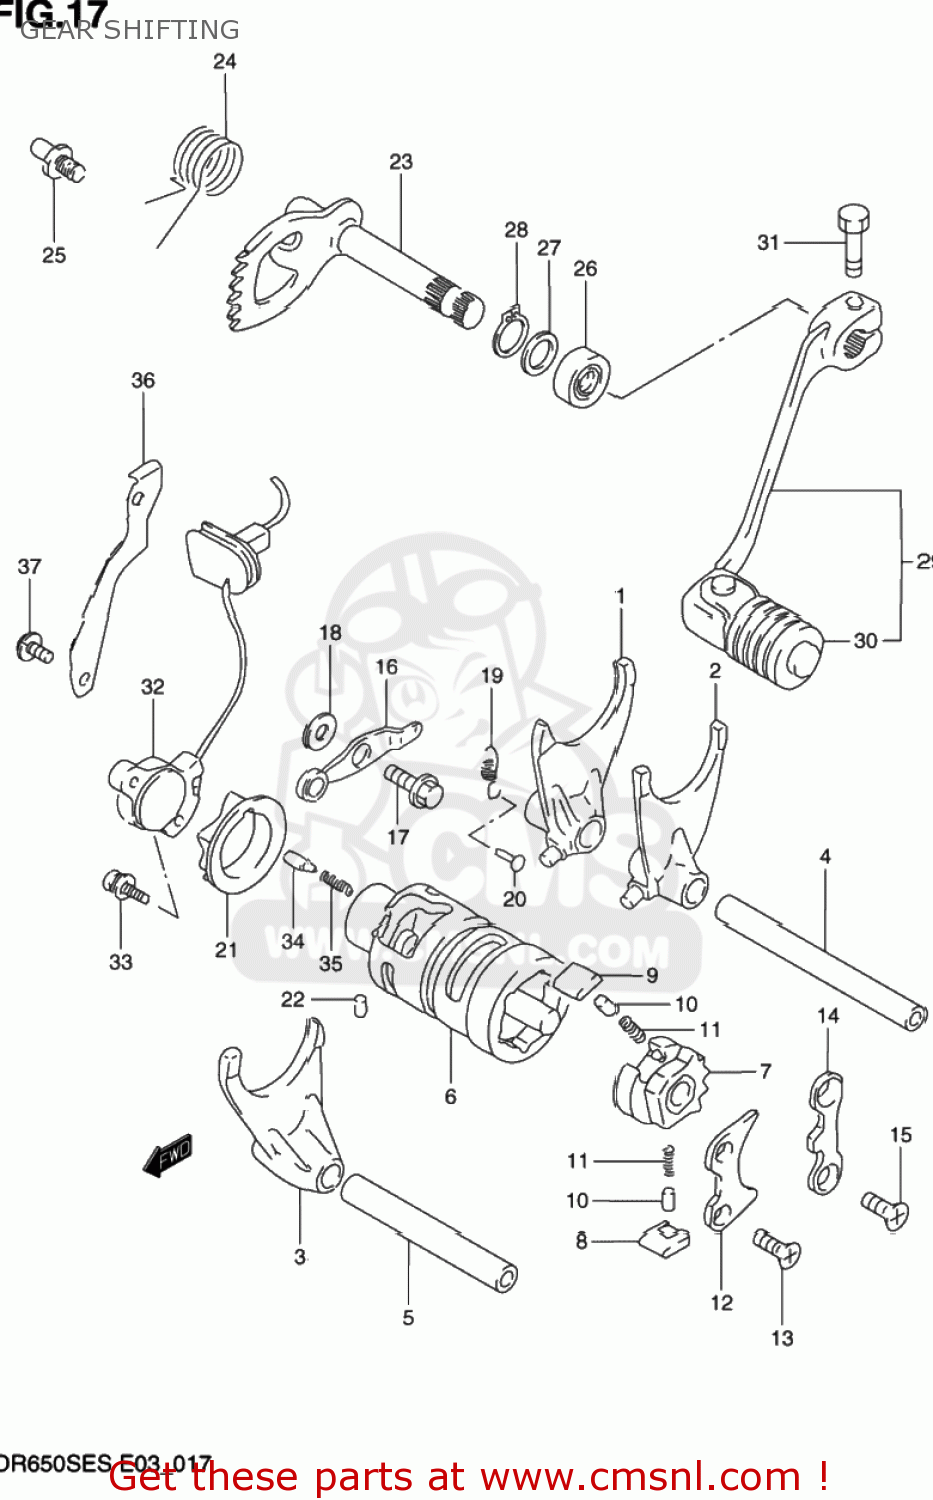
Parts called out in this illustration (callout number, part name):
1	FORK,GEAR SHIFT NO.1
2	FORK,GEAR SHIFT NO.2
3	FORK,GEAR SHIFT NO.3
4	SHAFT,GEAR SHIFT FORK
5	SHAFT,GEAR SHIFT FORK
6	CAM,GEAR SHIFT
7	GEAR,GEARSHIFT CAM DRIVE
8	PAWL,GEAR SHIFT NO.1
9	PAWL,GEAR SHIFT NO.2
10	PIN(5X8)
11	SPRING
12	LIFTER,GEAR SHAFT PAWL
13	SCREW
14	STOPPER,GEAR SHIFT POLE
15	SCREW
16	STOPPER,GEAR SHIFT CAM
17	BOLT
18	WASHER
19	SPRING
20	RIVET
21	PLATE,SHIFT CAM STOPPER
22	PIN 4X6
23	SHAFT,GEAR SHIFT
24	SPRING
25	STOPPER,GEAR SHIFT CAM
26	OIL SEAL
27	WASHER
28	CIRCLIP,12 MM
29	LEVER ASSY,GEAR SHIFT
30	RUBBER,GEAR SHIFT PEDAL
31	BOLT
32	BASE ASSY,NEUTRAL SW TERMINAL
33	SCREW
34	PIN(5X15.5)
35	SPRING
36	CLAMP,LEAD WIRE
37	SCREW
